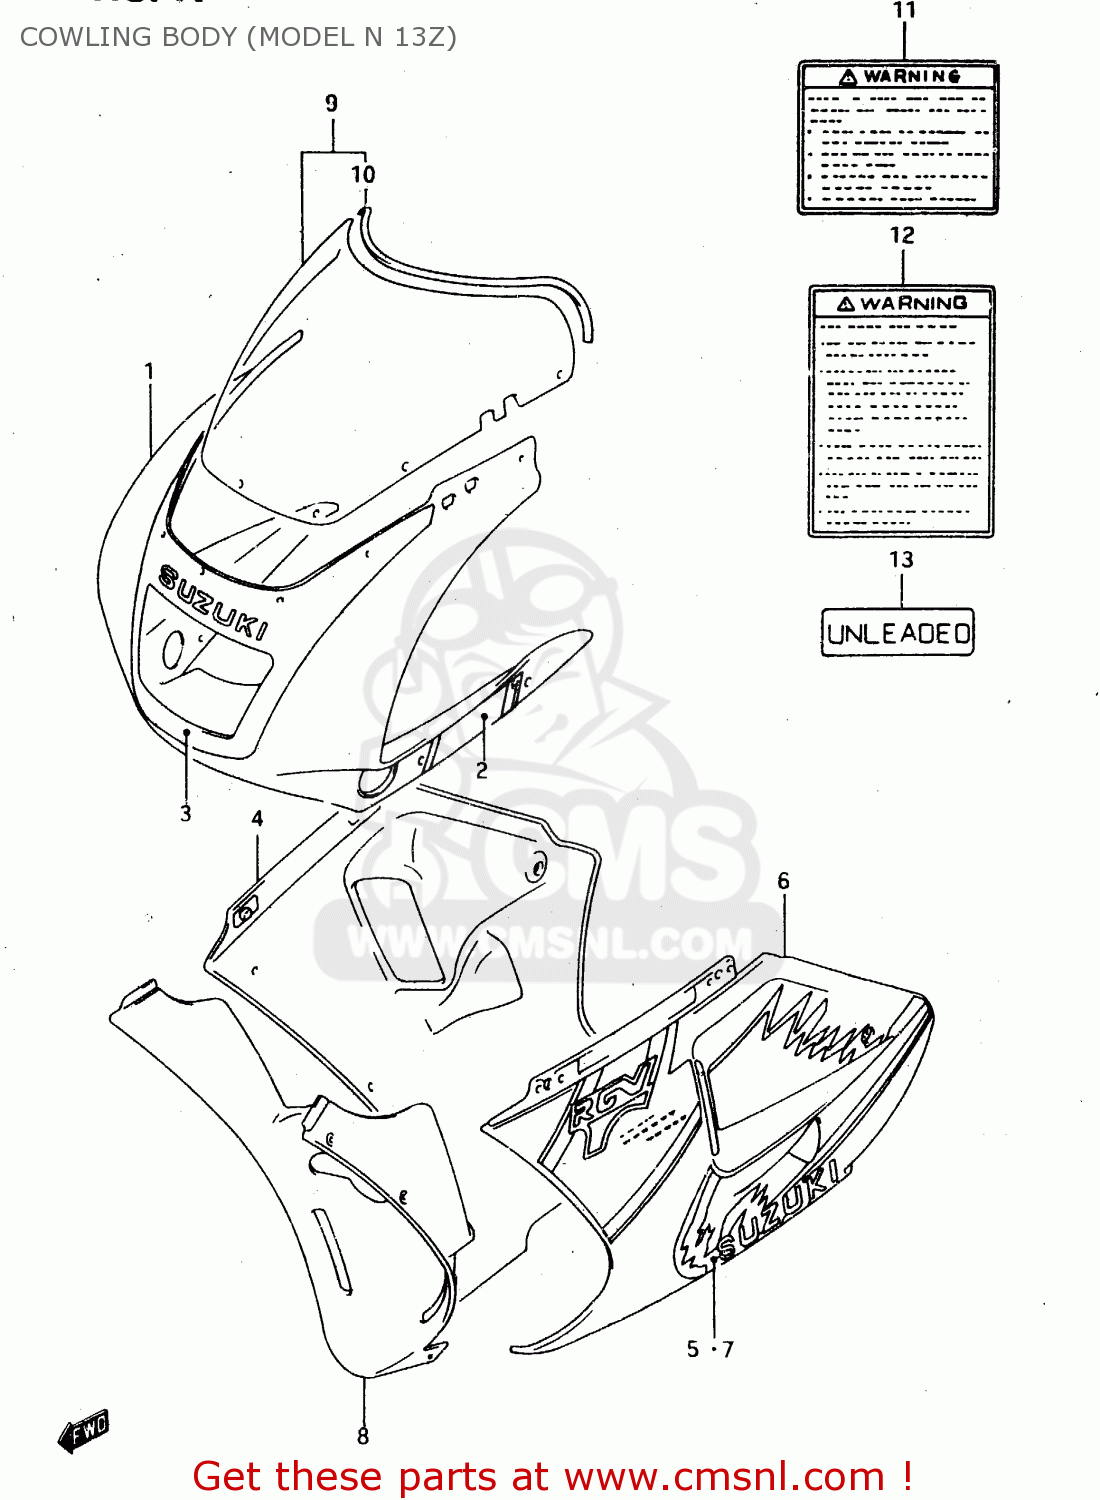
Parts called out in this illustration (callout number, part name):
1	COWLING ASSY, BODY (BLACK)
2	TAPE SET, SIDE
3	TAPE, ZECKEN
4	COWLING ASSY, UNDER RH (BLACK)
5	TAPE SET, UNDER RH
6	COWLING ASSY, UNDER LH (BLACK)
7	TAPE SET, UNDER LH
8	COWLING,UNDER CTR
9	SCREEN SET,WIND
10	MOLDING WINDSCREEN
11	LABEL
12	LABEL (WARNING SCREEN)
13	LABEL,CAUTION
